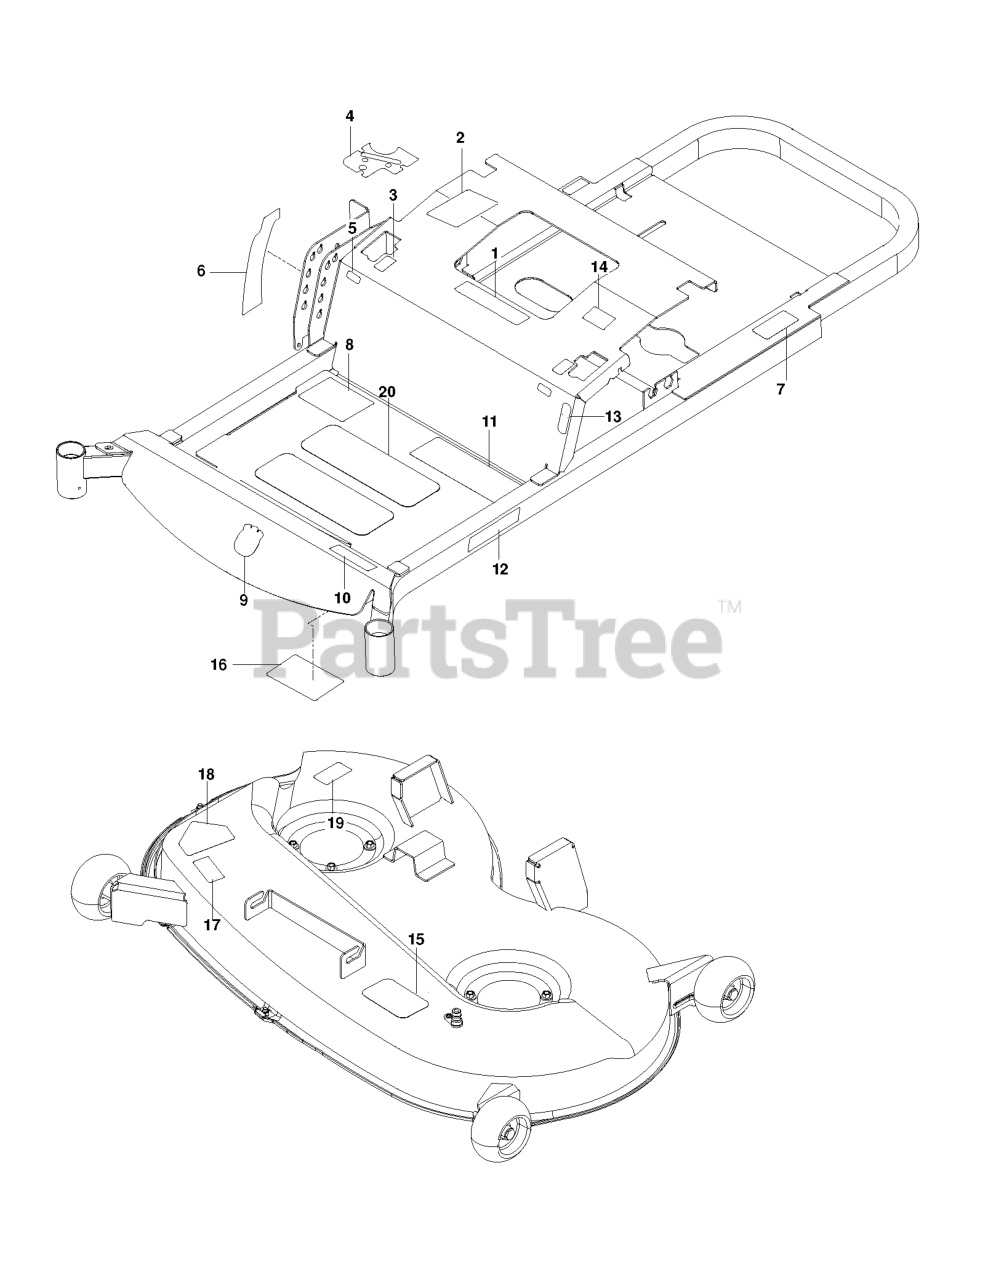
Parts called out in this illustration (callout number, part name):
1	EURO DECAL-BATTERY WARNIN6
2	DECAL, CUSTOMER RESPNSIBILITY
3	DECAL, MOTION CONTROL
4	DECAL, CTRL PANEL, HUSQ
5	DECAL, F.S.T.
6	DECAL, DECK HEIGHT, HUSQ
7	DECAL, DO NOT TOW
8	DECAL.ZTR.STRTNGINST.REMOTECHK
9	DECAL.AUGER.HUSQ.CROWN.SNOW
11	DECAL, SAFETY WARNING
12	RP.DECAL.BADGE.170MM.TEXTLOGO
13	DECAL, PARK BRAKE
14	DECAL, EXITING MOWER
15	DECAL, BELT ROUTING
16	DECAL, SERVICE
17	DECAL, EURO SEVERING
18	DECAL, DECK DEFLECTOR, WARNING
19	DECAL.DECK.6MIL./DEF.SHLD.WARN
20	ANTI-SKID PAD
